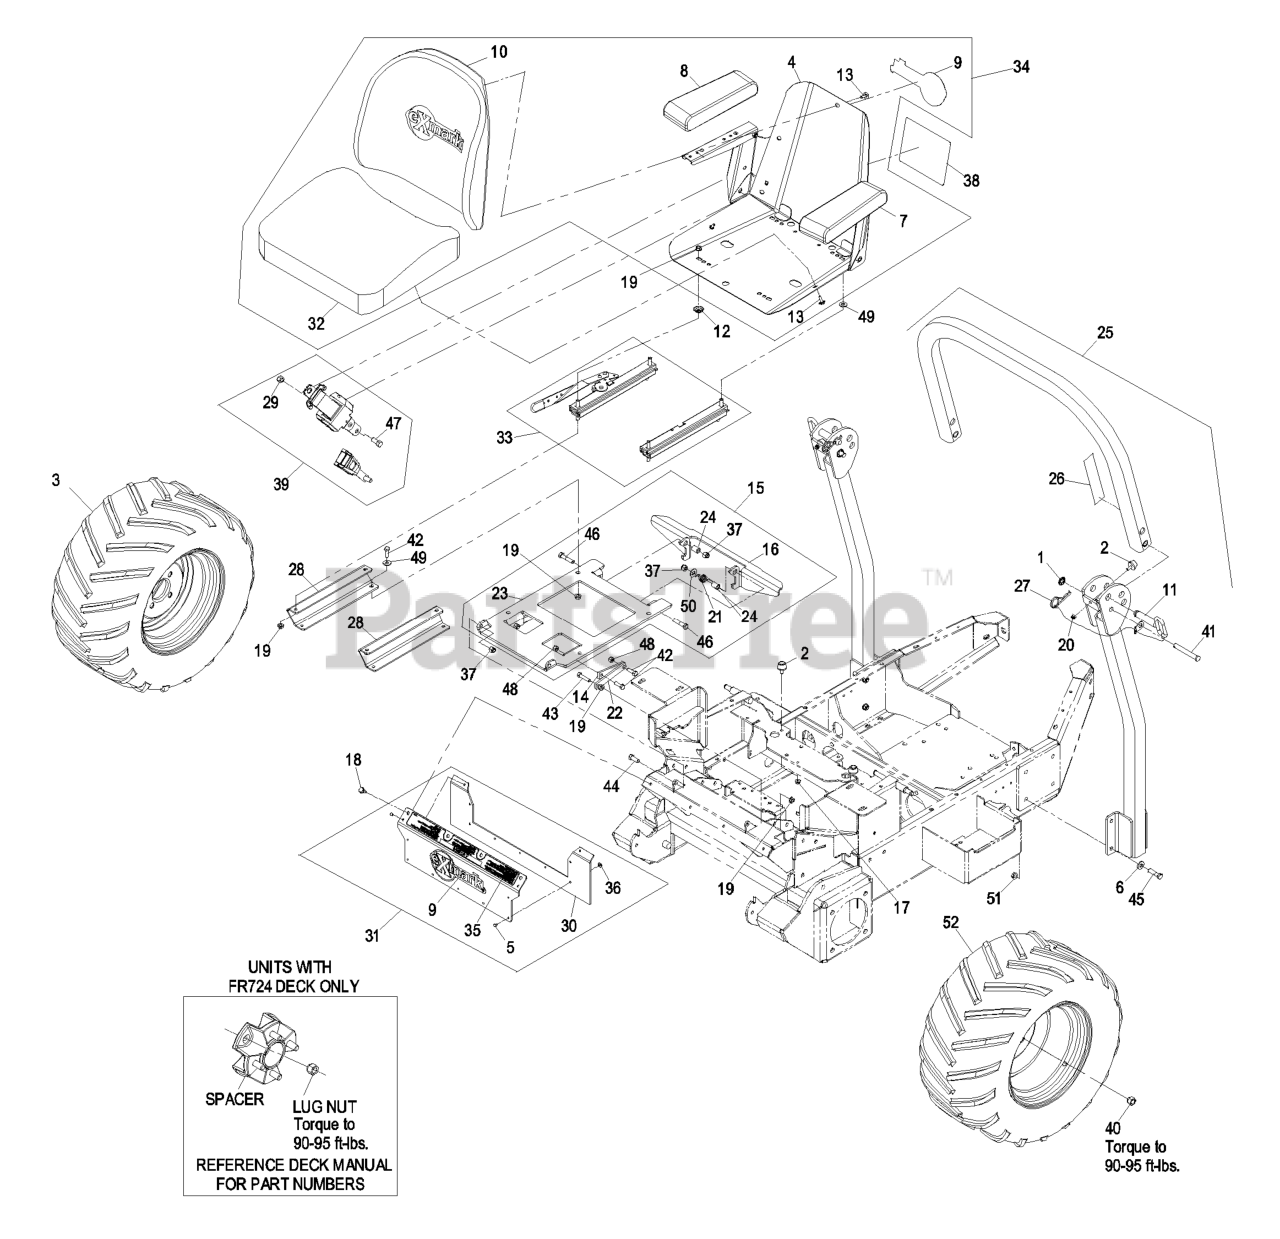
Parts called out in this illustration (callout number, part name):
1	NUT-PUSH
2	BUMPER-RUBBER
3	ASM,WHEEL AND TIRE LUG RH
4	FRAME-SEAT
5	RIVET-POP
6	WASHER-BELLEVILLE
7	CUSHION,ARMREST LH
8	CUSHION,ARMREST RH
9	DECAL,EXMARK LOGO
10	CUSHION,SEAT BACK
11	PIN-FOLD, ROPS
12	SPACER-TRACK
13	BOLT-SEAT
14	LINK-STOP, SEAT
15	ASM, SEAT FRAME FMZ
18	SCREW-HWH, THREAD CUT
20	NUT-LOCK, NI
22	LINK,FMZ LWR SEAT STOP (P
23	ASM, SEAT FRAME FMZ
24	BUSHING-LEVER, LIFT
25	KIT,ROPS FMZ
26	DECAL-WARNING, FOLDING RO
27	HAIRPIN
28	SUPPORT, ANGLED SEAT
29	NUT-LOCK
30	Skirt, Rubber
31	ASM,FRONT CONSOLE W/ DECA
35	DECAL,TOP CONSOLE
36	WASHER-FLAT
37	NUT-LOCK, NI
38	DECAL,FR SERVICE AID
39	RETRACTABLE SEATBELT KIT
40	NUT-LUG
41	PIN-CLEVIS
42	SCREW-HH
43	SCREW-HH
44	SCREW-HH
45	SCREW-HH
46	SCREW-HH
47	SCREW-HH
48	NUT-LOCK, NI
49	WASHER-FLAT
50	WASHER-FLAT
51	NUT-HHF, WHIZ
52	ASM,WHEEL AND TIRE LUG LH
